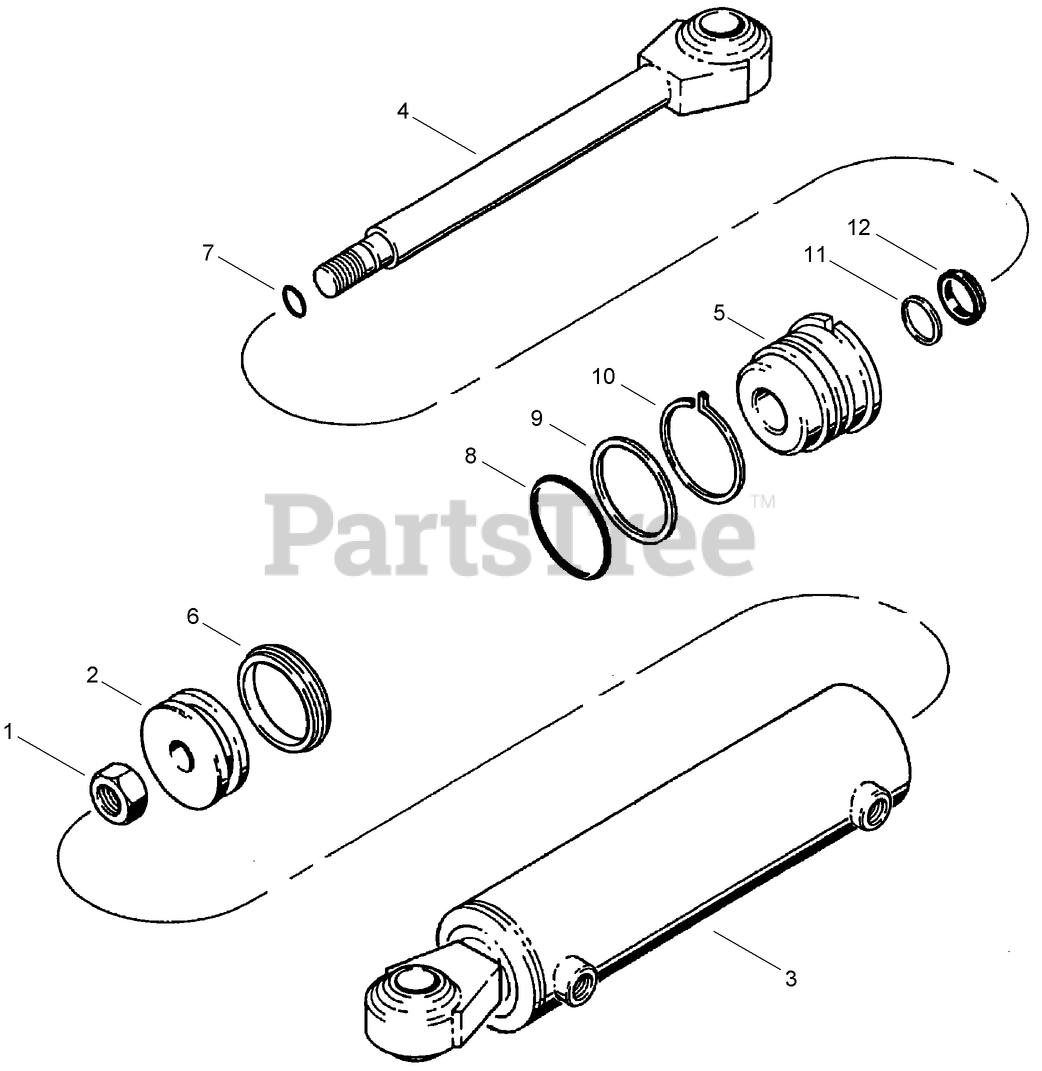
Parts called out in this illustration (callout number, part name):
1	NUT - Hex, Self-Locking, .75-16, 65 x 1.12
2	PISTON - Cylinder, 2.50 x 0.75
3	TUBE - Cylinder, 2.50
4	ROD - Piston
5	GLAND - Cylinder, 2.50 x 1.00
6	SEAL - Piston, Outer
7	O-RING
8	O-RING
9	RING - Backup, Gland O-Ring
10	WIRE - Gland Locking
11	SEAL - Rod
12	WIPER - Piston Rod
